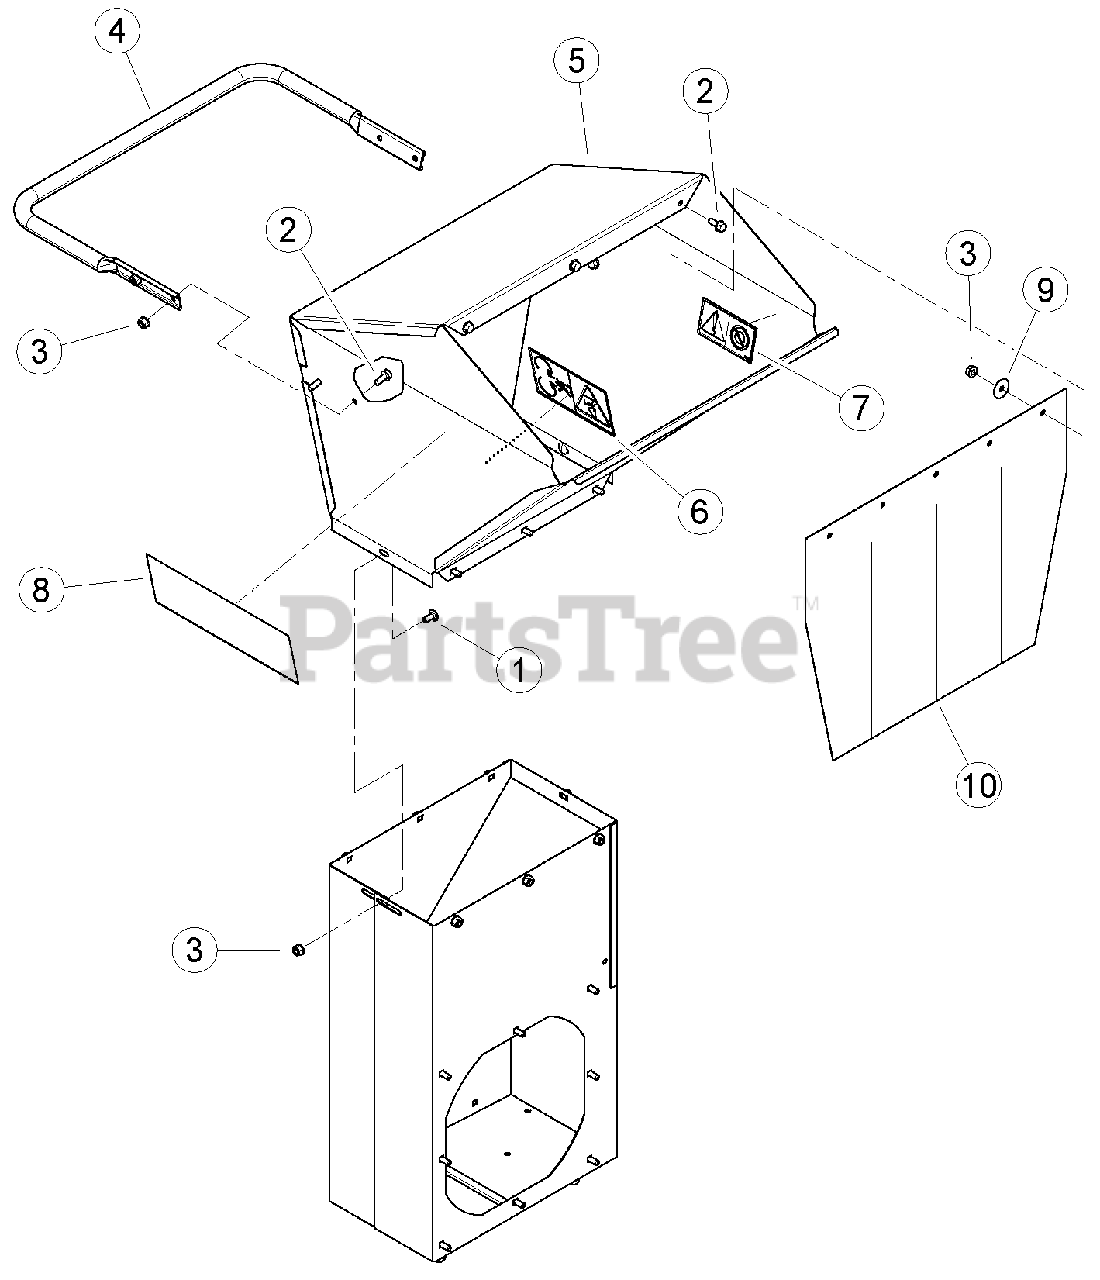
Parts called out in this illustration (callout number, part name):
1	BOLT, 5/16-18 X 3/4 CRG GR5 SN
2	BOLT, 5/16 X 3/4 FLANGE NC
3	NUT, 5/16-18 NYLOCK-FLANGE
4	HANDLE, EURO HOPPER
5	ASSEMBLY, EUROPEAN WIDE HOPPER
5	ASSEMBLY, NARROW EURO HOPPER (SC3206XE ONLY)
6	DECAL, BLADE DANGER ISO
7	DECAL, SHREDDER SIZE ISO
8	DECAL, ECHO BEARCAT 12.00 X 4.00
9	WASHER, 5/16" FENDER ZP
10	BELTING, EURO HOPPER
